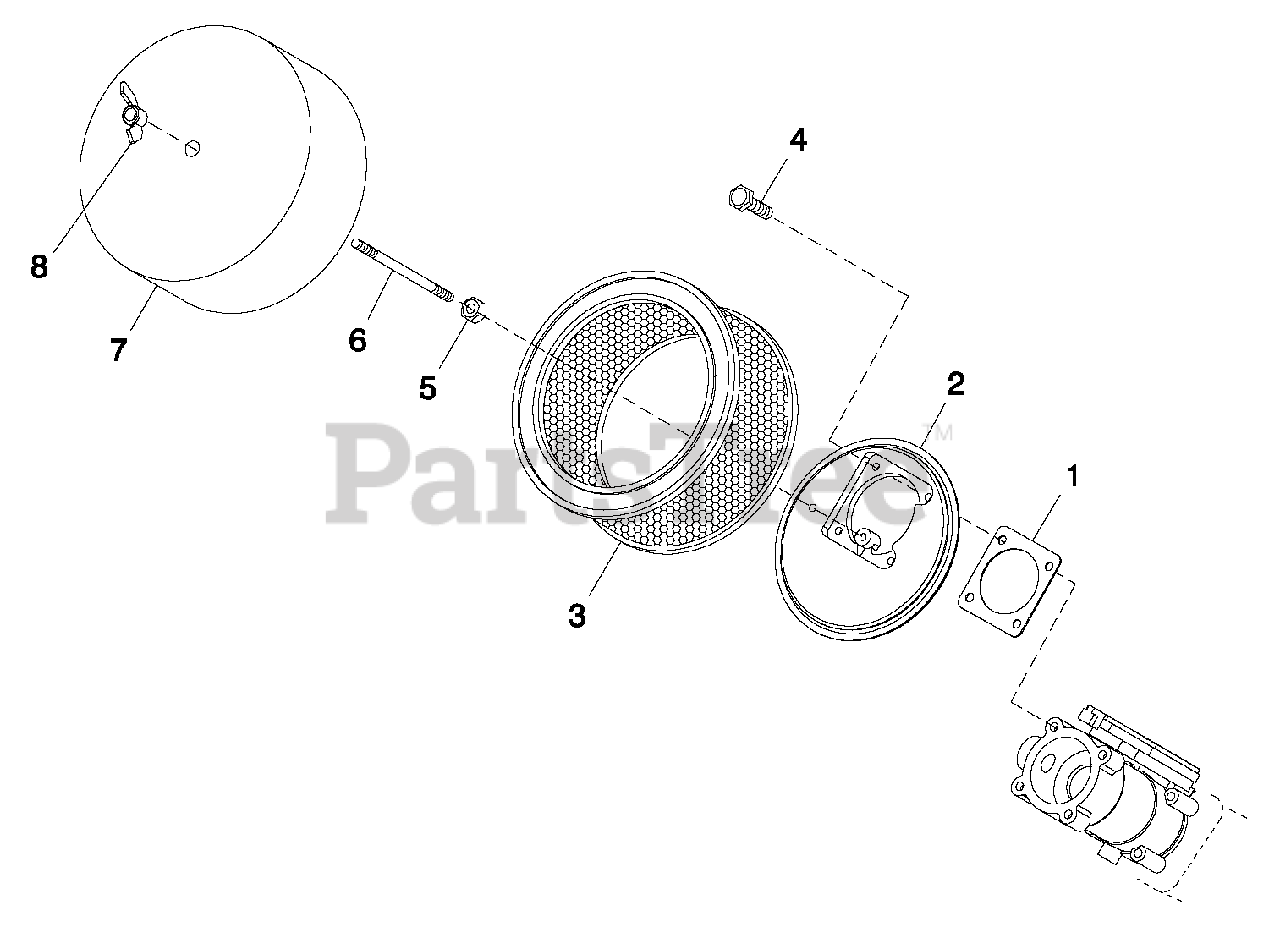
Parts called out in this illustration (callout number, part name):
1	GASKET BOSCH 32 & 40
2	ADAPTER CARBURETOR W/PVC CONN
3	ELE MENT AIR CLEANER
4	SCREW HHC M5-0.8X 16 G8.8
5	NUT HEX 1/4-20 STEEL
6	STUD TH 1/4-20 X 4-1/2 G2 ZNC
7	PLATE, AIR CLEANER TOP 2.4L
8	NUT WING 1/4-20 NYLK
